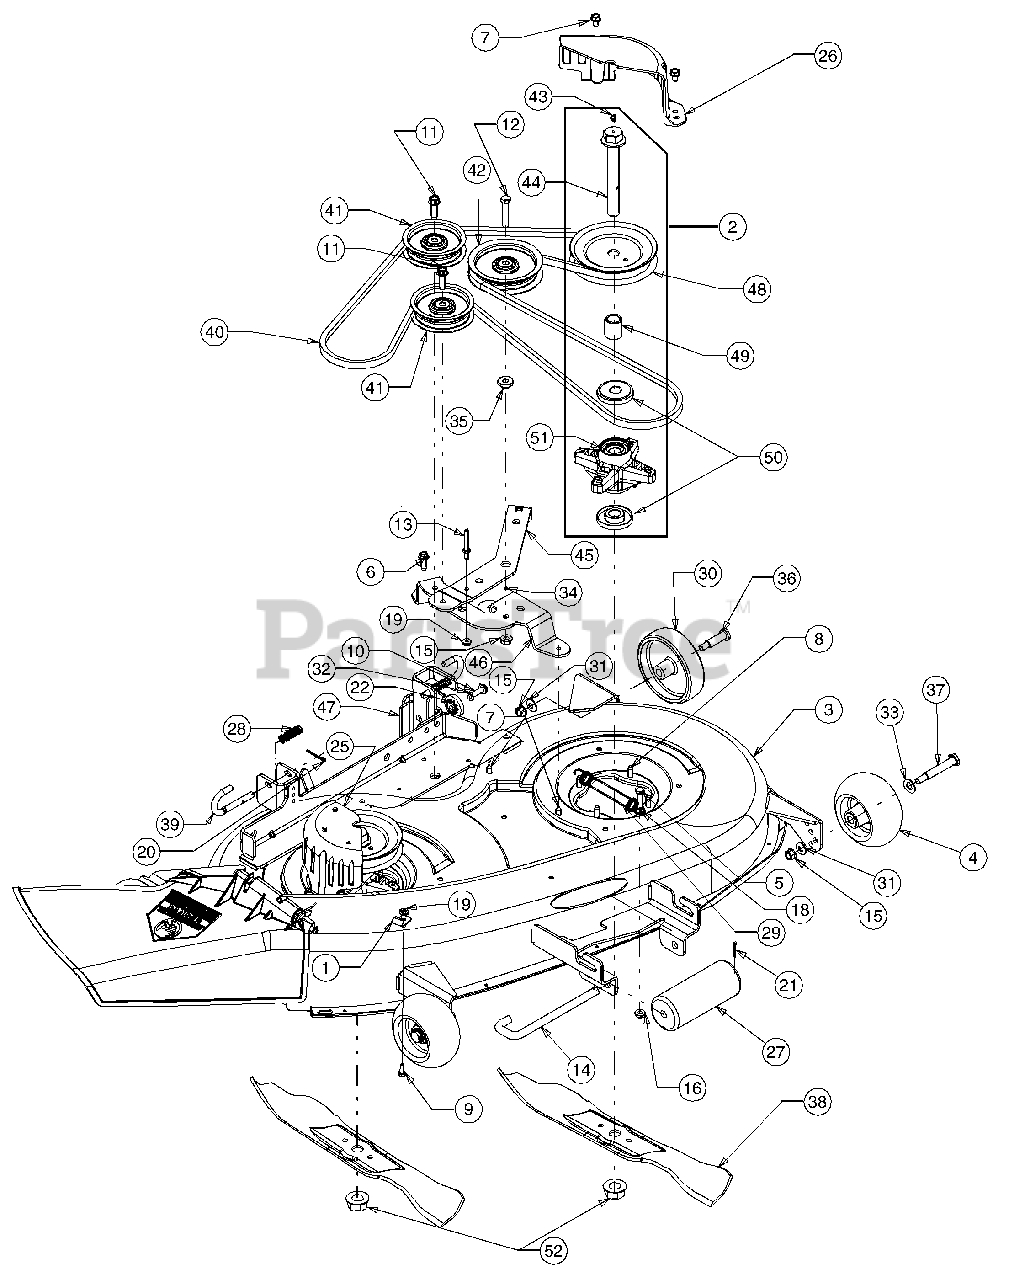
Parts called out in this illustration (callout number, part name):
1	Bracket, Hook, Retainer
2	Spindle Assembly, 38" (Not available as assembly)
4	Wheel, Deck, 5.0 OD w/ Fitting
5	Screw, 5/16-18, 1.25, Gr5
6	Screw, Self-tapping, 5/16-18, 1.000
7	Screw, 5/16-18, 0.625
8	Screw, Self-tapping, 5/16-18, 0.875
9	Screw, 1/4-20, .620, Gr5
10	Screw, Self-tapping, 5/16-18, 1.250
11	Screw, Self-tapping, 3/8-16, 1.250
12	Screw, 3/8-16, 2.00, Gr5
13	Pin, Guide, .250 Dia x 1.68 Lg
14	Roller Pin 1/2" x 7.31 Lg
15	Nut, Flange Lock, 3/8-16
16	Nut, Flange Lock, 5/16-18, Gr5
17	Nut, Hex, 1/4-20, Gr5
18	Nut, Hex, 5/16-18, Gr5
19	Nut, Flange Lock, 1/4-20
20	Pin, Cotter, 1/8 x 1.25
21	Pin, Cotter, 3/32 x 1.25
22	Adjustment Gear, Deck
23	Nut, Push, .25 ID x .50 OD
24	Chute Assembly, Side Discharge
25	Cover, Belt, Deck
26	Cover, Belt, Deck, LH
27	Front Roller
28	Spring, Compression, .406 x .531 x 1.75 Lg
29	Spring, Extension .94 x 7.57
30	Wheel Deck 5.0 x 1.38
31	Washer, Bell, .375 x .870 x .063
32	Washer, Lock, 5/16, Regular Duty
33	Washer, Flat, .510 x 1.00 x .060
34	Grease, Alvania Ep 2
35	Spacer, Shoulder, 1.00 x .38 x .38
36	Shoulder Screw
37	Shoulder Screw - 1/2 Dia x 2.50 Lg.
38	Blade, 19.38 Lg, 3-in-1
39	Rod, Handle, Deck Release .375 Dia
40	Belt, V-Type
41	Pulley, Idler, 3.50 Dia.
42	Pulley, Idler, 4.06 Dia. w/ Flange
43	Fitting, 3/16 Drive Lube
44	Bolt, Spindle, 3/4-16, 5.85 (solid bolt, no grease fitting)
44	Bolt, Spindle, 3/4-16, 5.85 Greaseable spindle (No longer available) replace with 710-04226, 618-04217 & 737-3000
49	Spacer, .80 x 1.10 x 1.330
50	Spacer, Spindle, Deck
51	Spindle Housing Assembly (Greaseable) Includes bearings and seals
51	Spindle Housing Assembly (Non Greaseable) Includes bearings and seals
52	Nut, Flange, 3/4-16
